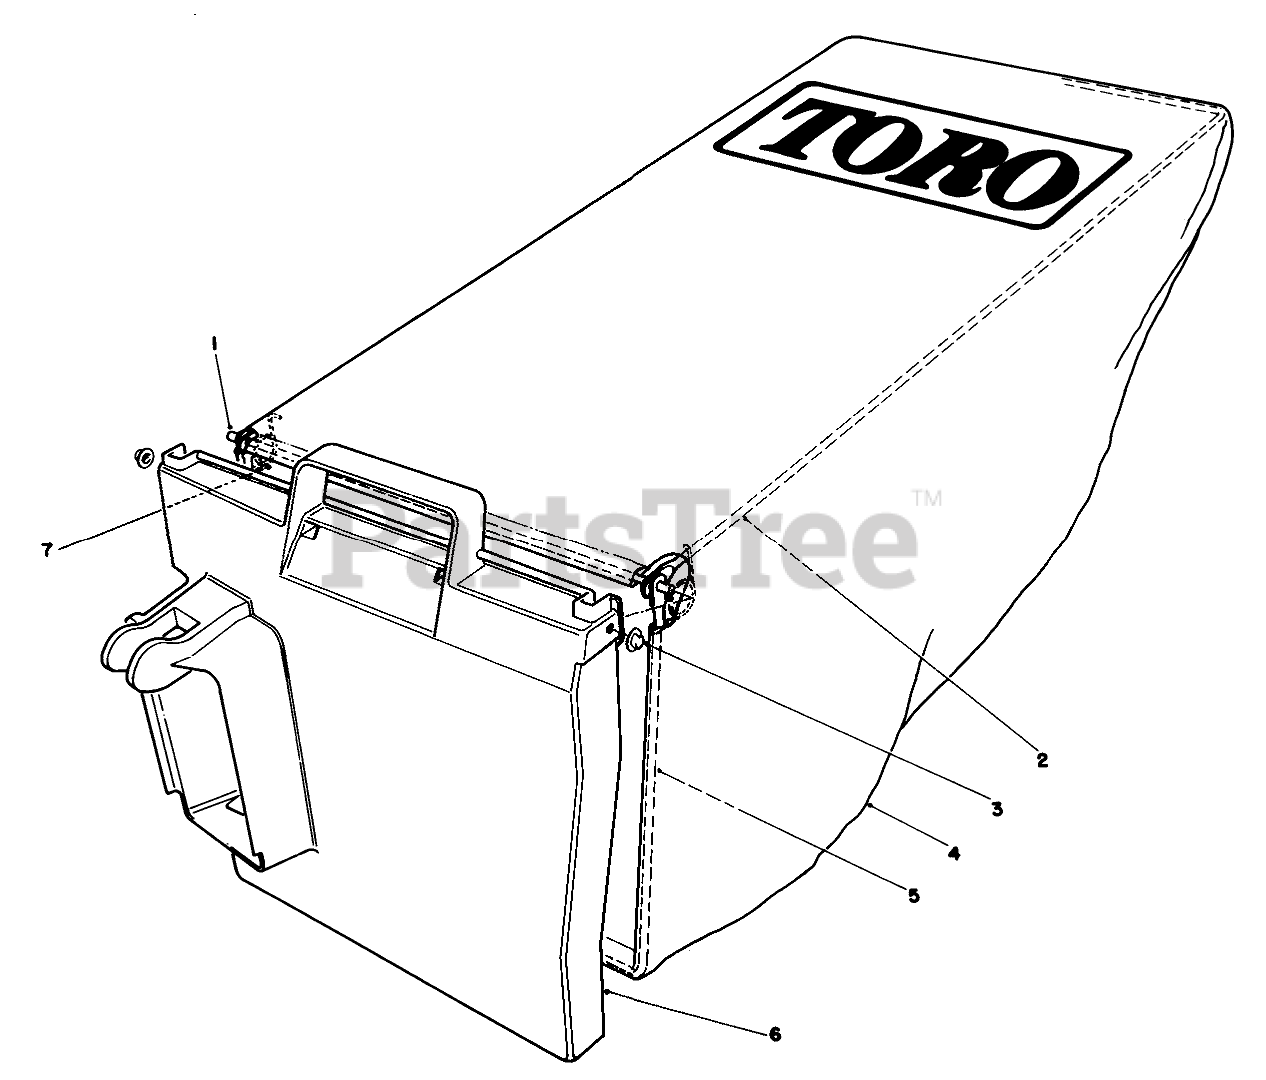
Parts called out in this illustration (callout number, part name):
1	HINGE PIN
2	BAG FRAME
3	NUT-PUSH
5	BAG FRAME
6	GRASS BAG DOOR
7	SPRING
